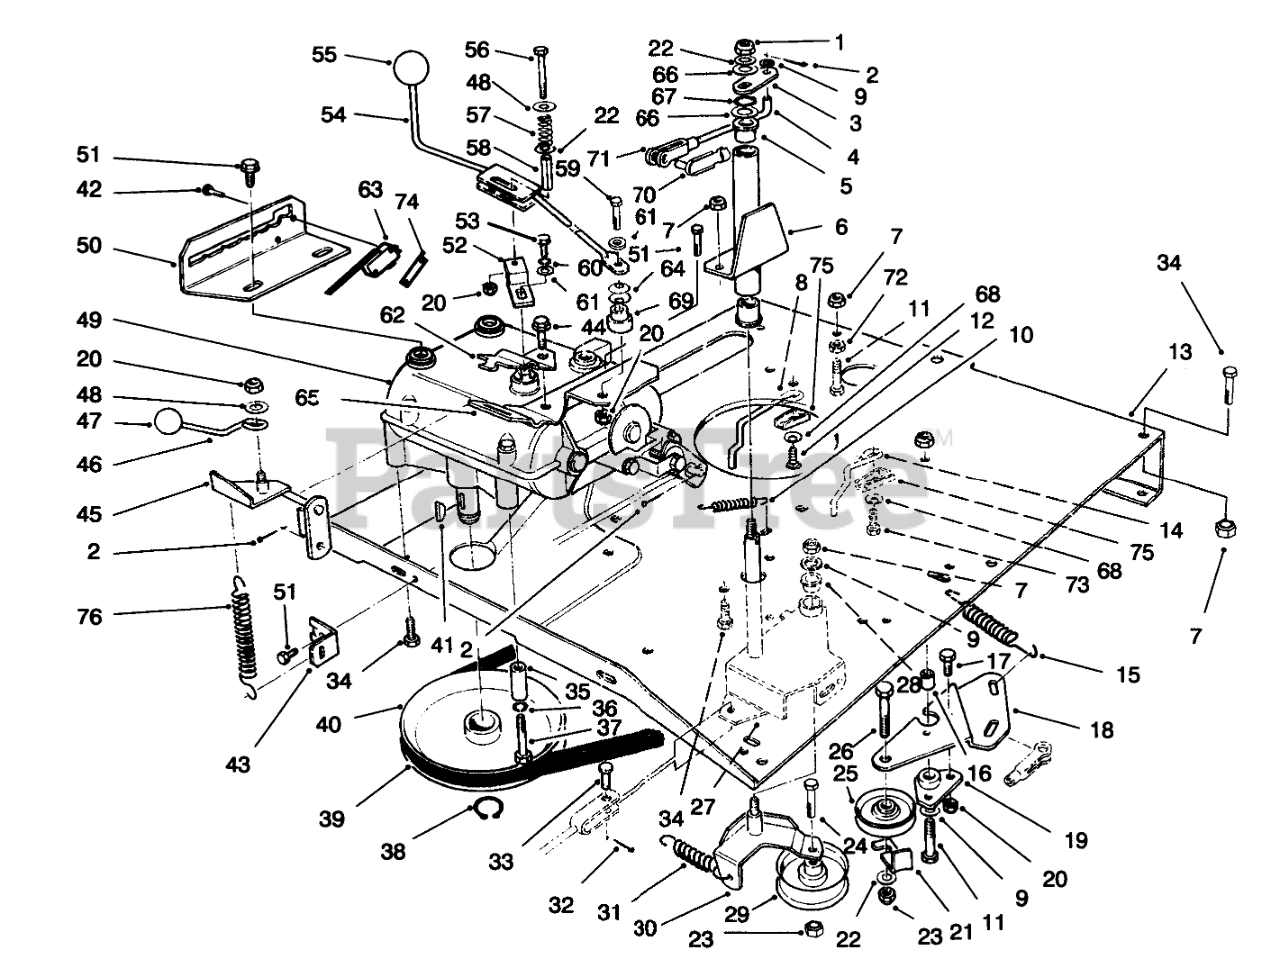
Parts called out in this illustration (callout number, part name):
1	NUT-LOCK, NI
2	PIN-COTTER
3	BRKT-DECK ENGAGE BLK
4	LINK-DECK ENGAGE
5	BUSHING-FLANGE
6	Tube W.A.-Pivot (Incl. Ref. #5)
7	NUT-LOCK, NI
8	ENG BELT GUIDE R.
9	WASHER-PLAIN
10	SPRING-RETURN, BRAKE
11	SCREW-HH
12	SCREW-HWHTF
13	PLATE-ENGINE
14	GUIDE-ENG. BELT L.
15	SPRING-TRACTION
16	SPACER-PIVOT
17	SCREW-HH
18	PLT-IDLER MTG
19	MOUNT-TRACTION PIVOT
20	NUT-LOCK, NI
21	RETAINER-BELT
22	WASHER-FLAT
23	NUT-LOCK, NI
24	SCREW-HH
25	PULLEY-IDLER
26	SCREW-HH
27	Bracket-Arm, Idler (Incl. Ref. #28)
28	BUSHING-FLANGE
29	PULLEY-IDLER
30	IDLER MTG PLT WA (BLACK)
31	SPRING-IDLER
32	PIN-COTTER
33	PIN-CLEVIS
34	SCREW-HH
35	GUIDE-BELT
36	WASHER-LOCK
37	SCREW-HH
38	RING-SNAP, EXTERNAL
39	67BELT, TRACTION DRIVE
40	PULLEY
41	KEY-WOODRUFF
42	SCREW-HH
43	BRKT-SPRING MT
44	SCREW-HWHTF
45	DECK ENGAGE LEVER WA (BLACK)
46	ROD-ENGAGE
47	KNOB-CONTROL
48	WASHER-FLAT
49	TRANSMISSION
50	Gate-Shift
51	SCREW-HWHTF
52	LEVER-SHIFT
53	SCREW-HH
54	SHIFT LEVER WA (BLACK)
56	SCREW-HH
57	SPRING-COMPRESSION
58	SPACER-SPLIT
59	SCREW-HH
60	WASHER-LOCK
61	WASHER-FLAT
62	BRKT-DECK ENG UPPER
63	SWITCH-MICRO
64	WASHER-BELLEVILLE
65	BRKT-DECK ENG. SHIFTER
66	WASHER
67	RING-RETAINING
68	WASHER-BELLEVILLE
69	SPACER-PIVOT
70	CLEVIS PIN ASM
71	CLEVIS-ADJ
72	NUT-JAM
73	BOLT-CARR
74	NUT-SPEED
75	ANCHOR-GUIDE, BELT
76	SPRING-DOOR
